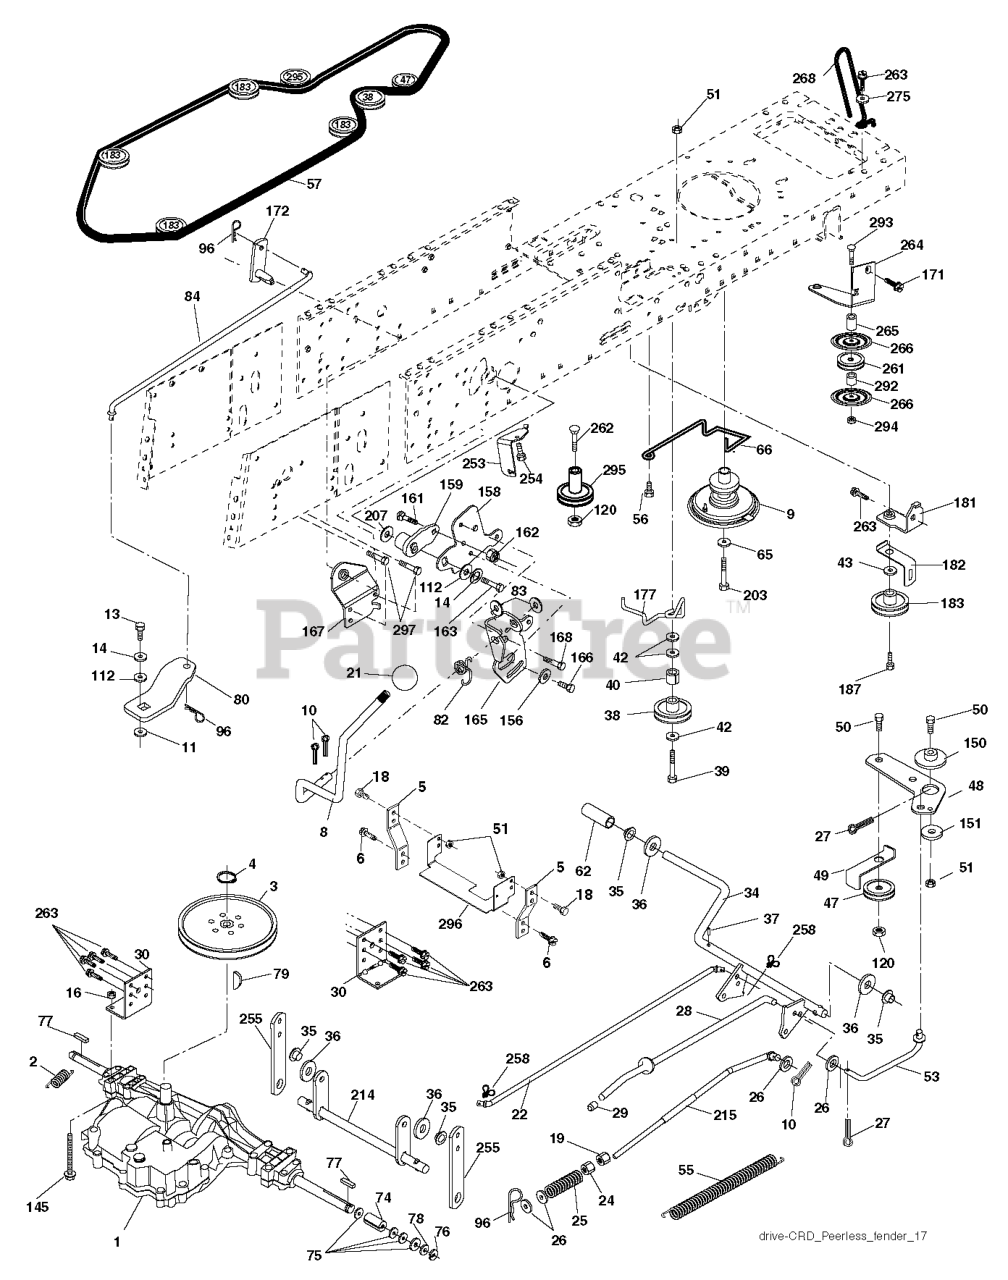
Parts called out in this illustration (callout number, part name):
2	SPRING,BRAKE RETURN
3	PULLEY
4	RETAINING RING LT
5	STRAP TORQUE
6	SCREW 5/16"
8	ROD SHIFT FENDER ADJUST LT
10	PIN COTTER
11	WASH-SHFT PLT LT
13	BOLT 1/4-28X3/4
14	LOCKWASHER
16	NUT.71038.31-18.HEX.NYLOCK
18	BOLT
19	NUT
21	KNOB T (1/2-HOLE)
22	ROD
24	NUT
25	SPRING ROD LT
26	WASHER
27	COTTER PIN
28	ROD, PARKING BRAKE
29	PLUNGER CAP
30	BRKT, MOUNT TRNSAXLE
34	SHAFT, FOOT PEDAL
35	BEARING.NYLON
36	WASHER LT
37	DRIVE PIN
38	PULLEY.FLAT
42	WASHER
43	WASHER T
47	IDLER PULLEY
48	BELLCRANK, CLUTCH
49	RETAIN BELT
50	BOLT.3/8-16X1.50
53	LINK.CLUTCH.7.66.2005
55	SPRING, RETURN LT
56	SCREW.3/8-16
57	V-BELT.KEV.111"
62	PEDAL COVER T
65	LOCKWASHER
66	KEEPER BELT ENGINE
74	SPACER AXLE
77	SQUARE KEY
79	KEY STD (1373) DANA
82	SHIFT SPRING
83	WASHER
96	RETAINER M
112	WASHER LT
120	NUT LOCK FLG 3/8-16 UNC
145	BOLT
150	BUSHING.BELLCRANK.GRD.DR
151	WASHER 12/32X2X10GA
156	WASHER.SRRTD.5/16
158	BRACKET.SHIFT.MOUNT
161	BOLT
162	NUT.CROWNLOCK.1/4
163	BOLT
165	BRACKET.PIVOT.LEVER
166	CAPSCREW.HXHD.FLG.5/16-18X.625
167	BRACKET.SUPT.SHIFT.CRD
168	BOLT.SHOULDER.5/16-18X
171	SCREW LT
172	SHAFT
181	BRACKET
182	BELT GUIDE
183	PULLEY.V-IDLER.
187	BOLT.5/16-18X1.25
203	BOLT.HEX.7/16-20 X 5
207	WASHER NYL
214	LEVER
254	SCREW 3/8-16X1
255	SHAFT
258	CLIP RETAINER
261	FLAT IDLER PULLEY
263	SCREW, 3/8-16X3/4
264	BRACKET.IDLER.CHASS.NORAM.2010
266	PROTECTOR
268	GUARD MUFFLER
275	WASHER
292	SPACER
293	BOLT.RDHD SQNK 3/8-16 X 3-1/2
294	NUT.HEX.3/8-16
295	PULLEY IDLER COMPOSITE
297	SCREW LT.3/8-46X5/8
